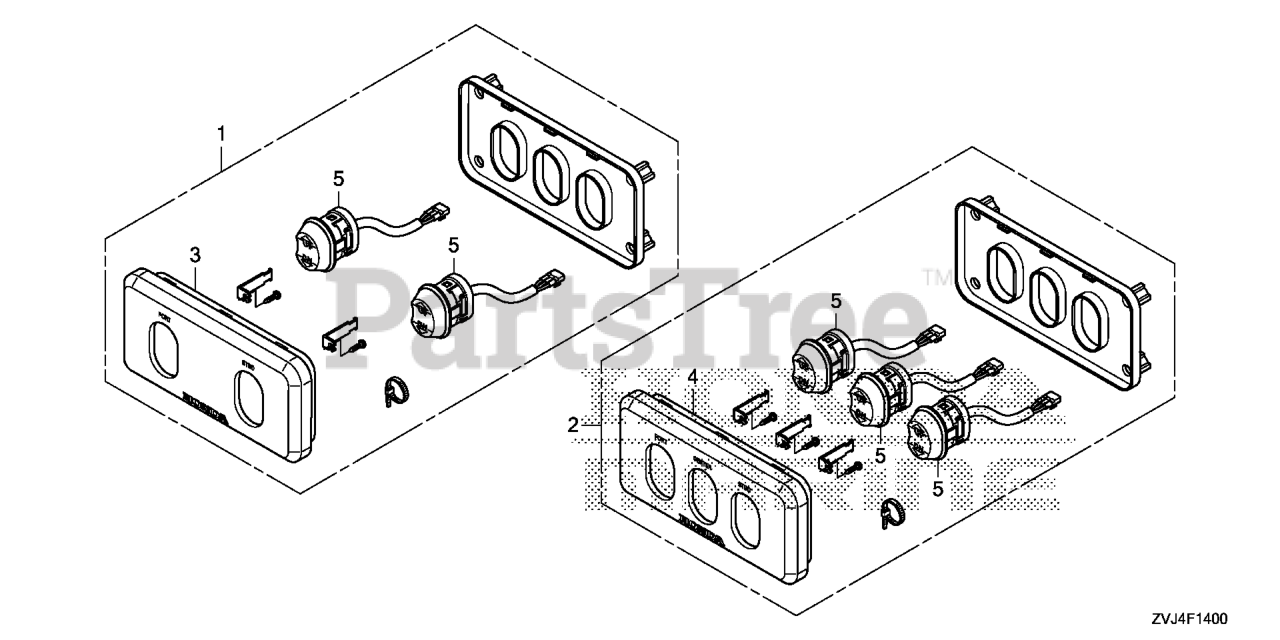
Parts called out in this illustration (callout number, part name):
2	PANEL ASSY., POWER TRIM-TILT SWITCH (TRIPLE)
4	PANEL, POWER TRIM-TILT SWITCH (TRIPLE)
5	SWITCH ASSY., POWER TILT
